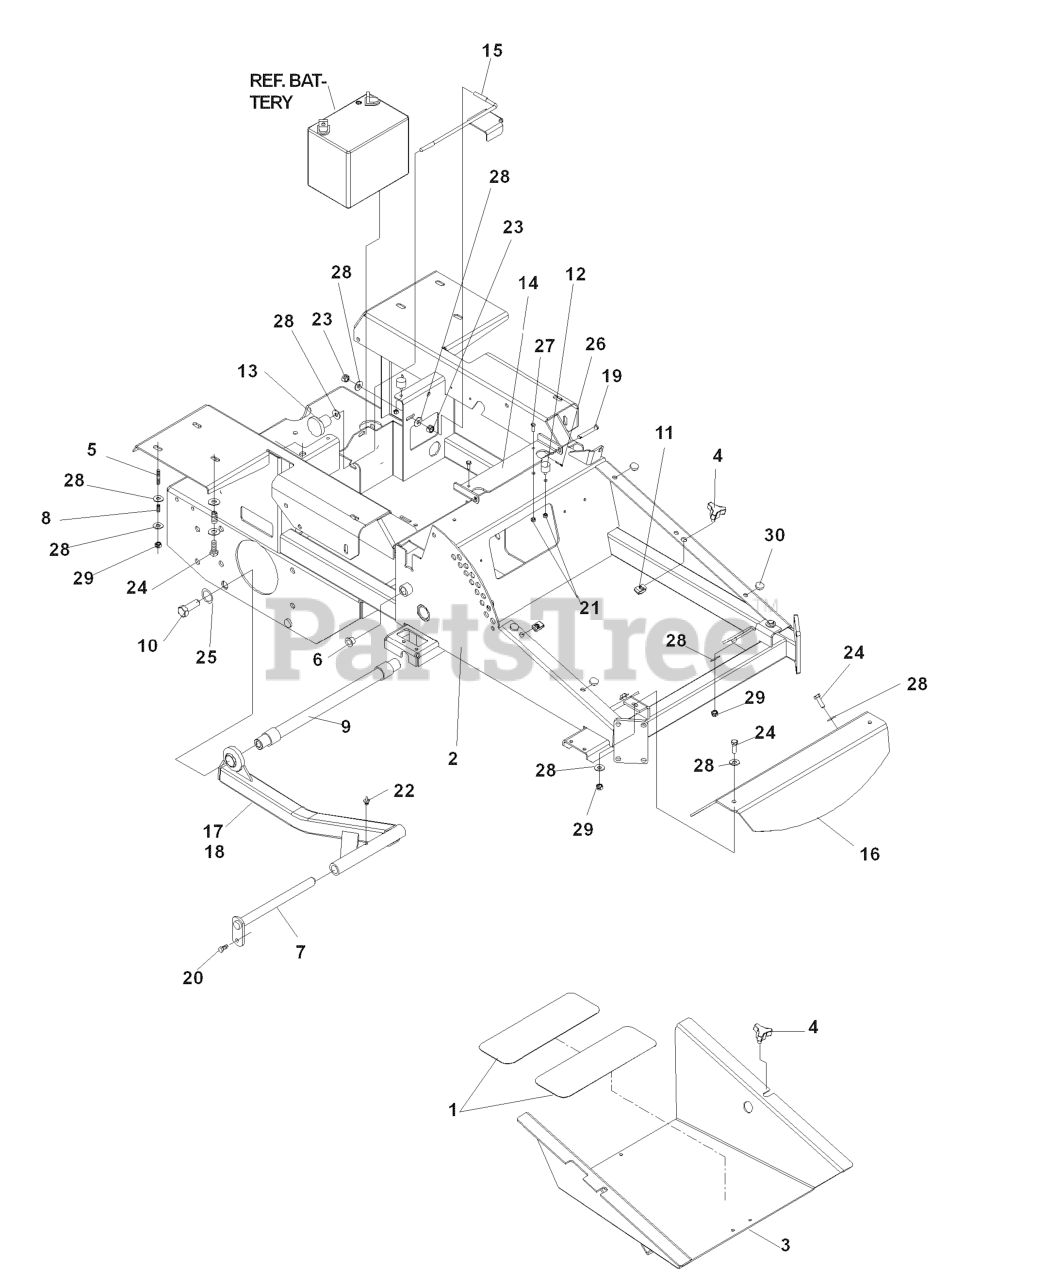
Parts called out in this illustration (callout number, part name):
1	ANTI-SKID PAD
2	IZ FRAME W/DECALS
3	IZ FOOTPLATE W/DECAL
5	STUD, 5/16C
9	STRUT MOUNT WELDMENT
10	HCS 5/8C X 2 GR.5
11	U-CLIP 5/16-18 NUT RETAINER
12	STUD/PLATE MOUNT
14	SEAT BRKT W/DECAL
15	BATTERY HOLD DOWN
16	FOOTREST ORANGE
19	CLEVIS PIN 3/8
20	HCS 5/16C X 3/4
21	NUT.1/4-20.HEX.NYLOC.ZD
22	ZERK
23	NUT 5/16C CENTERLOCK
24	HCS 5/16C X 1
25	LOCKWASHER 5/8
26	RP_COTTER PIN 1/8 X 3/4
27	HCS 1/4C X 3/4 HCS
28	WASHER 5/16 FLAT
29	NUT 5/16 NYLOC
30	GROMMET, BUMPER
